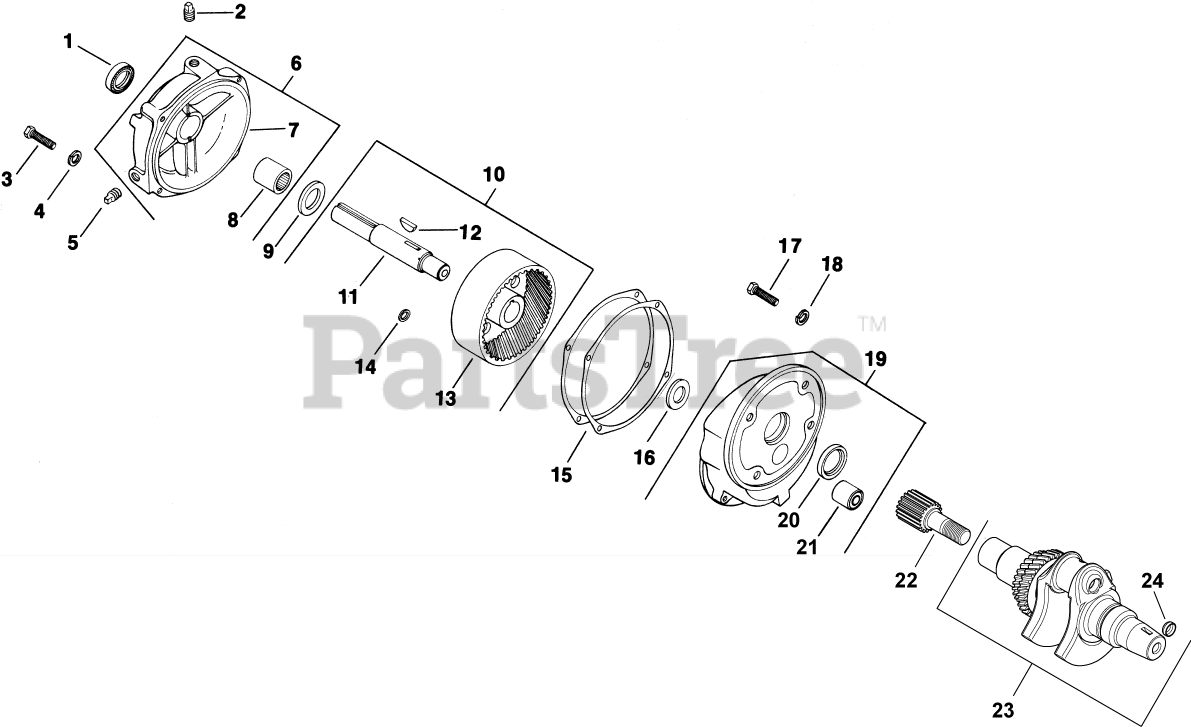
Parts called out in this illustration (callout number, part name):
1	SEAL - DISCONTINUED
3	SCREW,CAP HD 5/16-18x2"
4	WASHER, SPRING LOCK 5/16"
5	PLUG, MAGNETIC DRAIN
6	COVER ASSEMBLY, GEAR - DISC.
7	COVER - DISCONTINUED
8	BEARING - DISCONTINUED
10	GEAR ASSEMBLY, REDUCTION
11	SHAFT - DISCONTINUED
12	KEY, 3/16" X 1"
13	GEAR, REDUCTION
17	SCREW - DISCONTINUED
18	WASHER, SPRING LOCK 3/8"
19	HOUSING ASSEMBLY, GEAR - DISC.
20	SEAL, OIL - DISCONTINUED
21	BEARING
22	GEAR, CRANKSHAFT - DISCONTINUED
23	CRANKSHAFT
